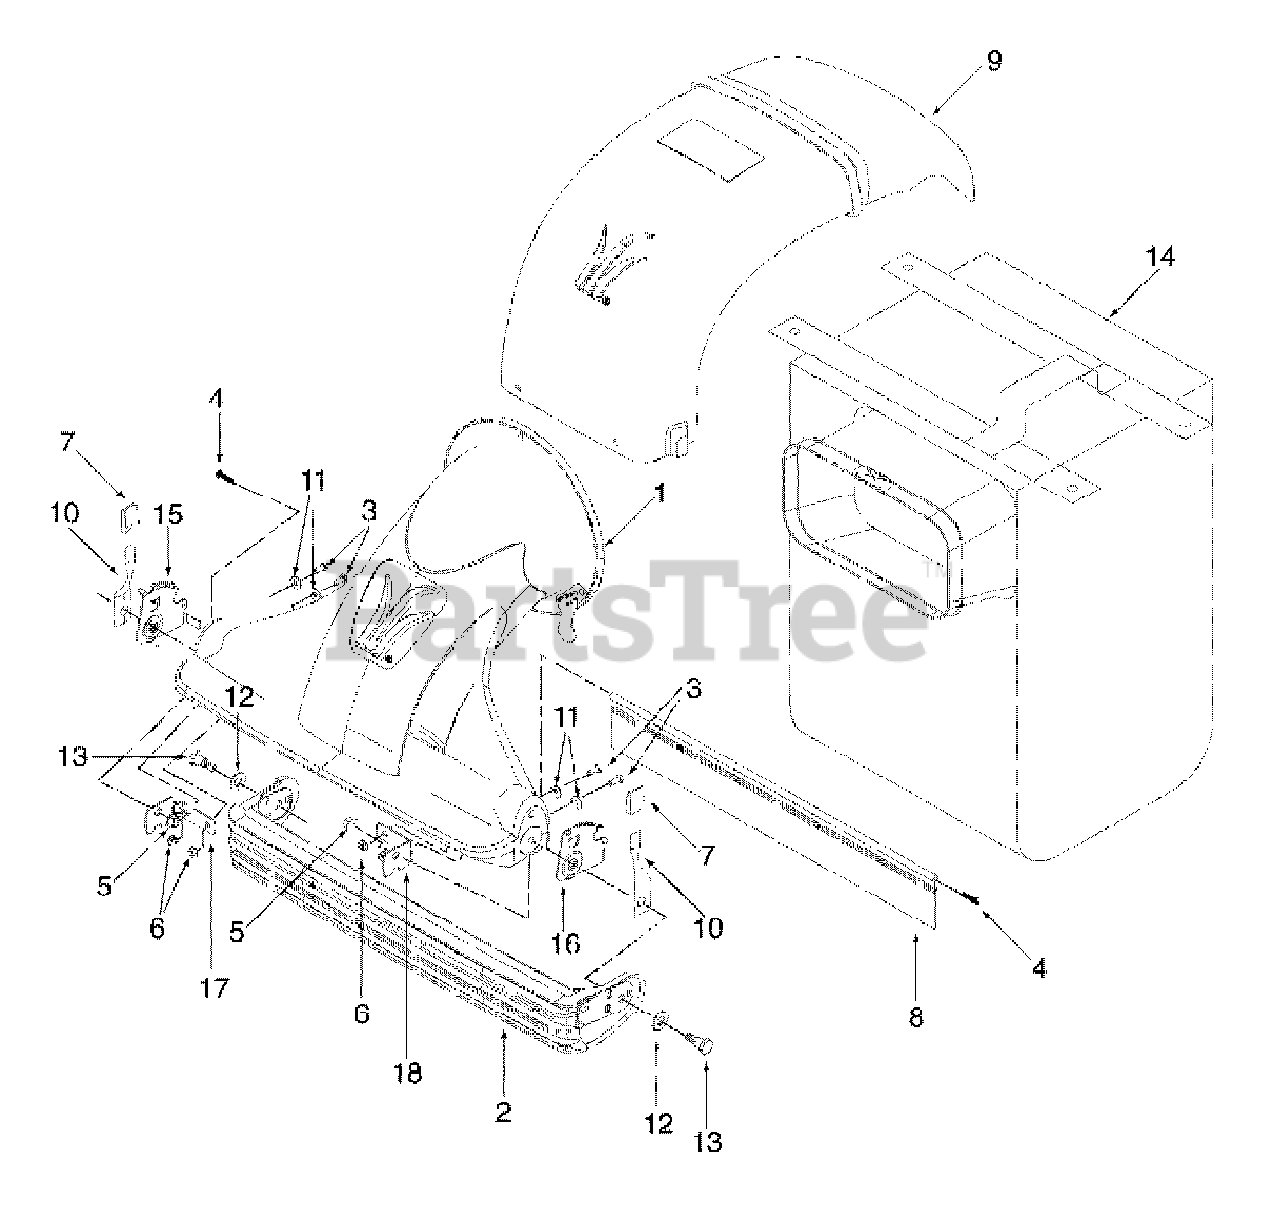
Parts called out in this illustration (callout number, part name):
1	NOZZLE ASSEMBLY
2	DOOR ASSEMBLY
3	HEX CAP SCREW 1/4-20 x .625
4	PHILLIPS TRUSS SCREW-HI-LO #12 x 1.00
5	FLANGED LOCK NUT 3/8-16
6	HEX FLANGED LOCK NUT 1/4-20
7	HEIGHT ADJUSTMENT KNOB
9	DISCHARGE CHUTE
10	SPRING LEVER
11	FLAT WASHER .28 - .74id. .063od.
12	FLAT WASHER .510 - 1.120 x .060
13	SHOULDER SCREW .5 x .545 x 3/8-16
14	3 BUSHEL BAG
